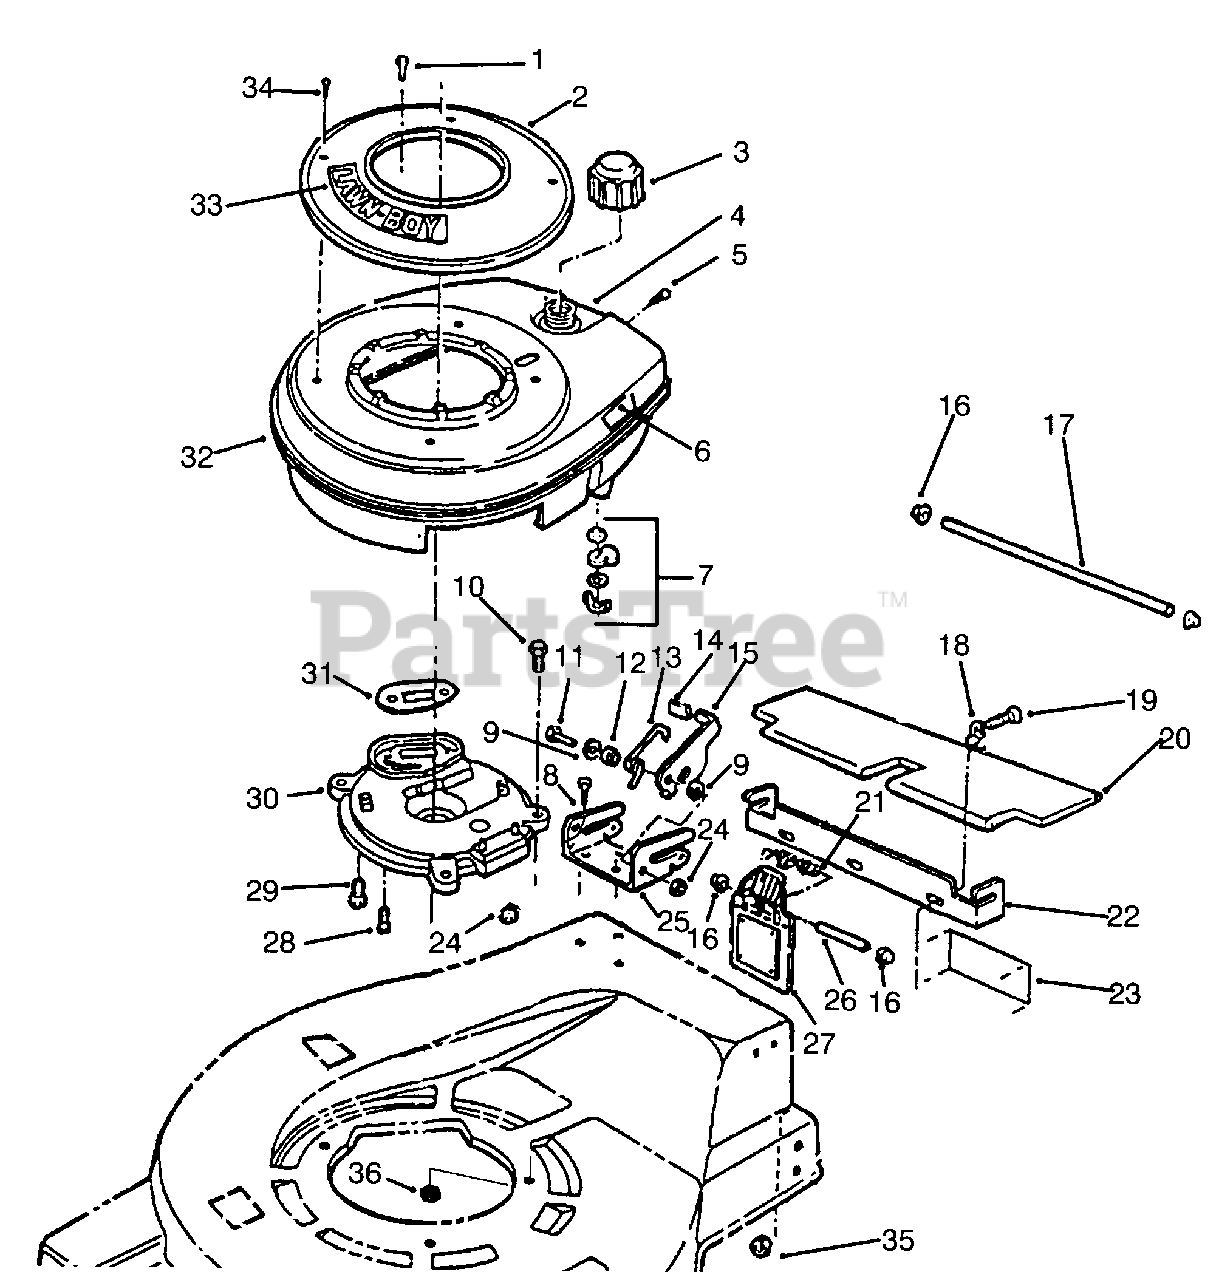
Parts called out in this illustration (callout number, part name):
1	Screw-Starter
2	Base-Starter
3	Assembly-Cap, Fuel (Incl. the following 2 items.)
4	Decal-Fuel Mix
6	Decal-Fuel Shut Off
7	Valve-Fuel Shut Off
8	Screw-Bracket, Rear Bag
9	Washer-Latch, Bag
10	Screw-Plate, Muffler
11	Screw-Latch to Bracket
12	Spacer-Latch/Spring Plate
13	Spring-Latch
14	Knob-Latch
15	Latch-Bag
16	Nut-Push
17	Rod-Shield, Trailing
18	Clamp-Rod, Trailing
19	Screw-Hanger, Bag
20	Shield-Trailing
21	Spring-Door
22	Bracket-Hanger, Bag
23	Decal-Caution, Discharge
24	Nut-Lock
25	Bracket-Mounting, Bag
26	Rod-Pivot, Door
27	Door-Discharge, Rear
28	Screw-Muffler Plate to Eng.
29	Screw-Muffler Plate to Eng
30	Plate-Muffler
31	Gasket-Exhaust
32	Assy.-Shroud/Tank & Valve (Incl. Ref. #7)
33	Appligue-Base, Starter
34	Screw-Shroud to Base
35	Nut-Lock
36	Nut-Muffler Plate to Hsg.
